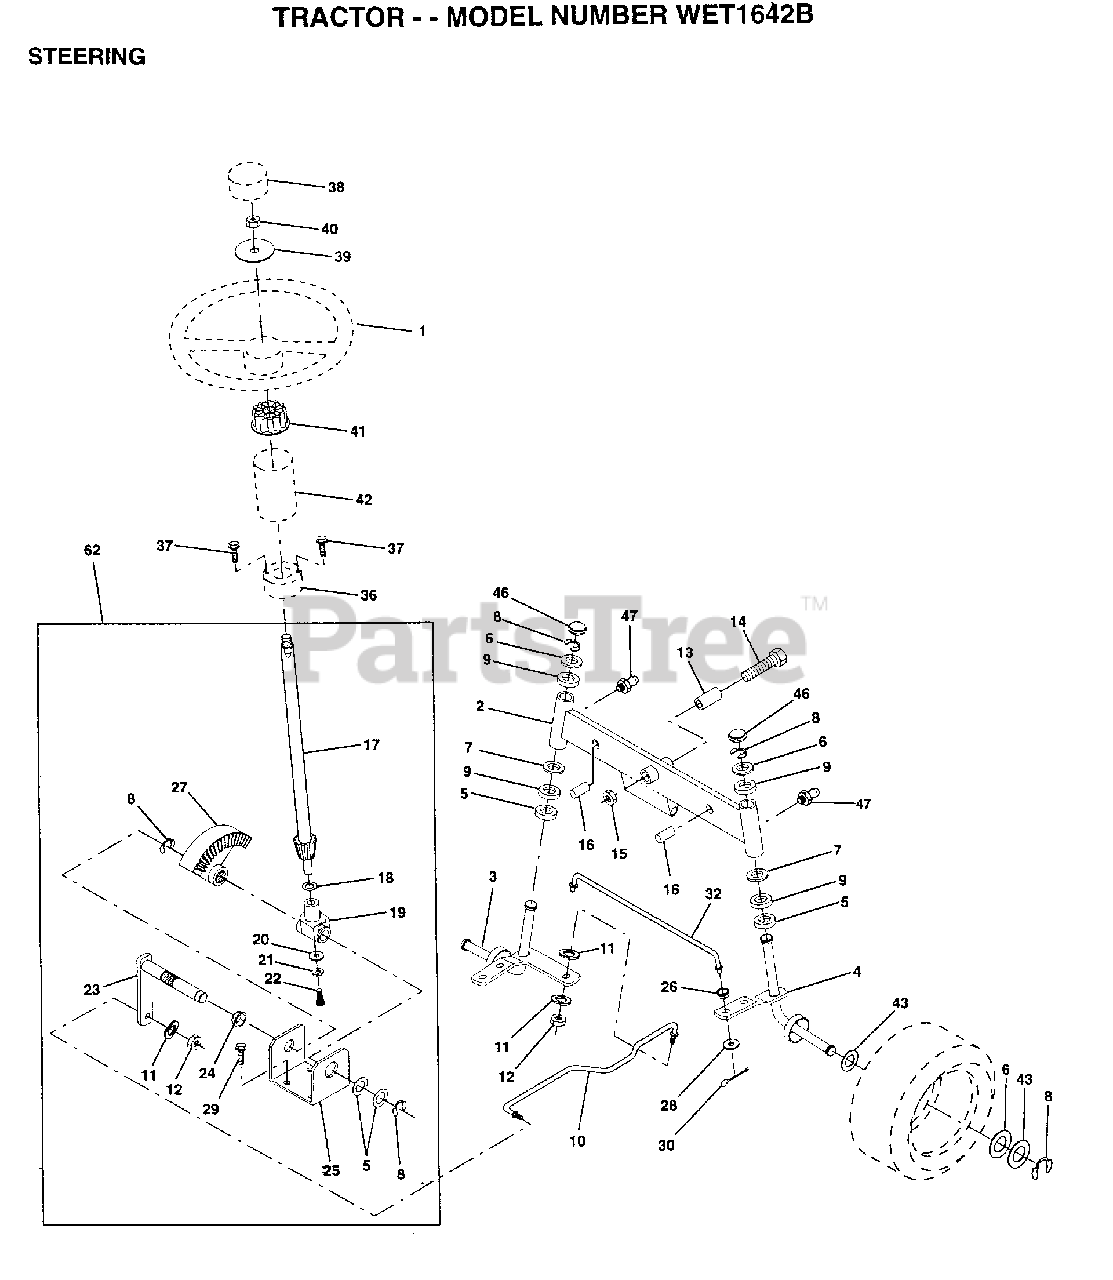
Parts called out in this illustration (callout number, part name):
2	AXLE ASM FRONT
3	SPINDLE LH
4	SPINDLE RH
5	WASHER .T
6	WASHER
7	WASHER
8	RING
9	COL. SRTG. BEAR.
11	LOCKWASHER
12	GRIPCO NUT
13	BEARING
14	BOLT HEX 5/8-11
15	"NUT-LOC,FLANGE LT"
16	AXLE PIN
17	SHAFT ASM
18	THRUST WASHER
19	SUPPORT.SHAFT
21	LOCKWASHER
22	SCREW.SCKTHD.CAP
24	NYLINER T
25	"BRKT,STEERING"
26	BUSHING.DRAGLINK
27	GEAR SECTOR
28	WASHER
29	SCREW
30	COTTER PIN
32	TIE ROD
37	"SCREW-TT,10-32 FL"
38	ST WHL INSERT CAP
39	WASHER T
40	GRIPCO NUT
41	ADAPTER-WHEEL LT
42	"TUBE, STR SHAFT"
43	WASHER
46	CAP
47	ZERK M
